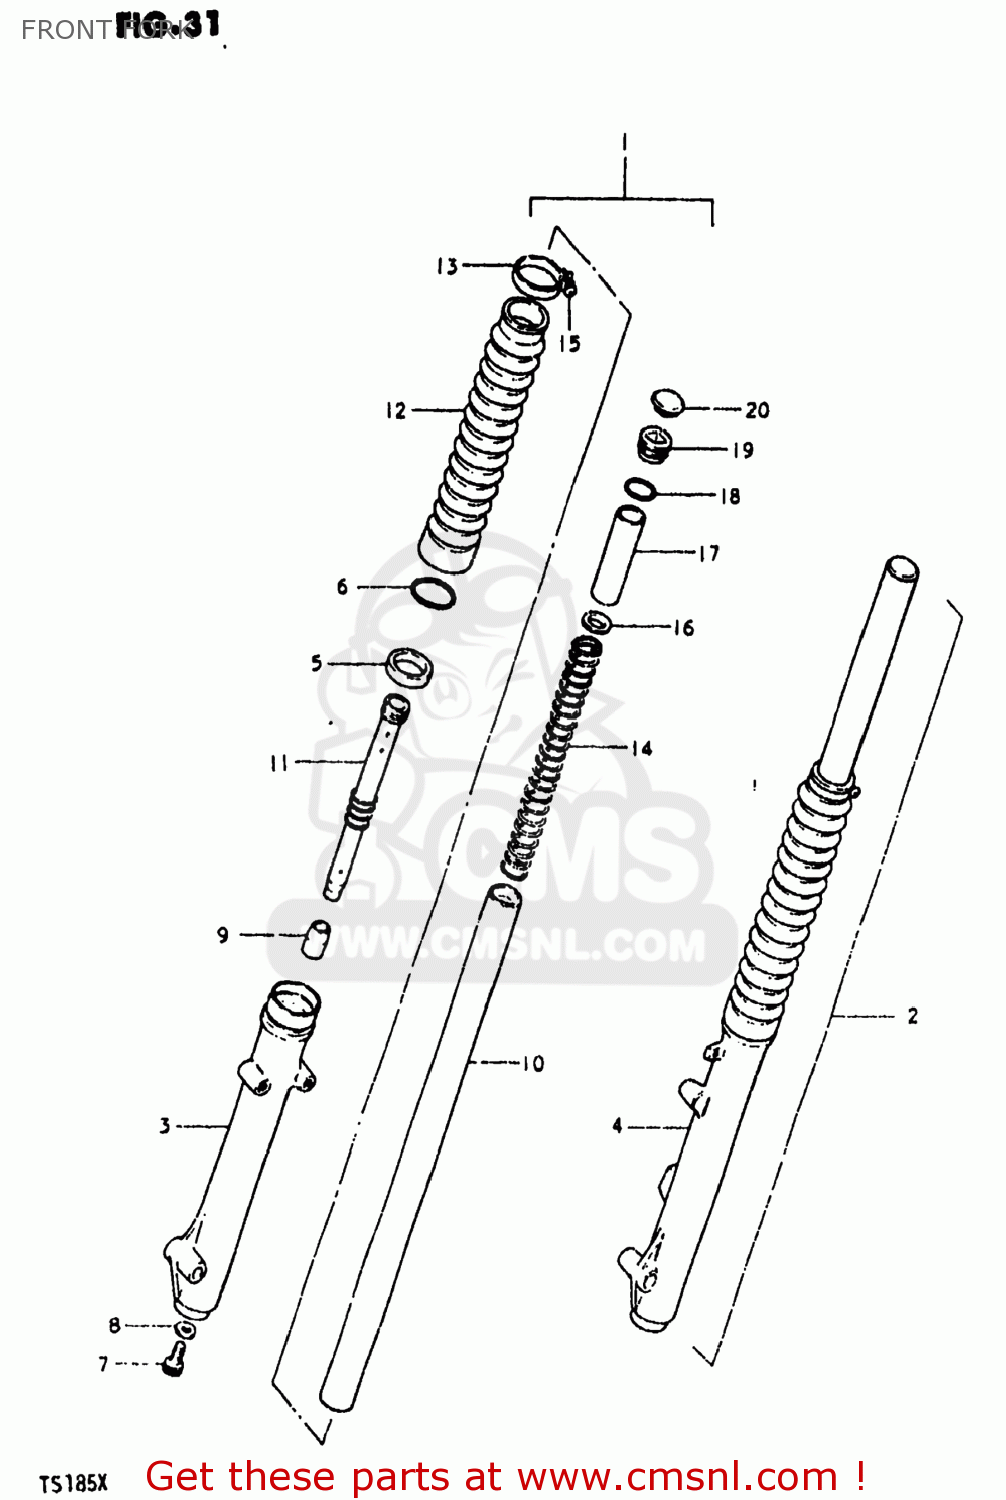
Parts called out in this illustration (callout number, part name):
1	DAMPER ASSY,FR FORK,R
2	DAMPER ASSY,FR FORK,L
3	TUBE,OUTER,R
4	TUBE,OUTER,L
5	SEAL,OIL
6	RING,STOPPER
7	BOLT,FORK CYLINDER(10X25)
8	GASKET (NAS)
9	PIECE,OIL LOCK
10	TUBE,INNER
11	CYLINDER
12	BOOT (BLACK)
13	BAND
14	SPRING
15	SCREW
16	GUIDE,SPRING COVER
17	SPACER,SPRING
18	O-RING,FORK INNER TUBE
19	CAP
20	CAP,FRONT FORK
